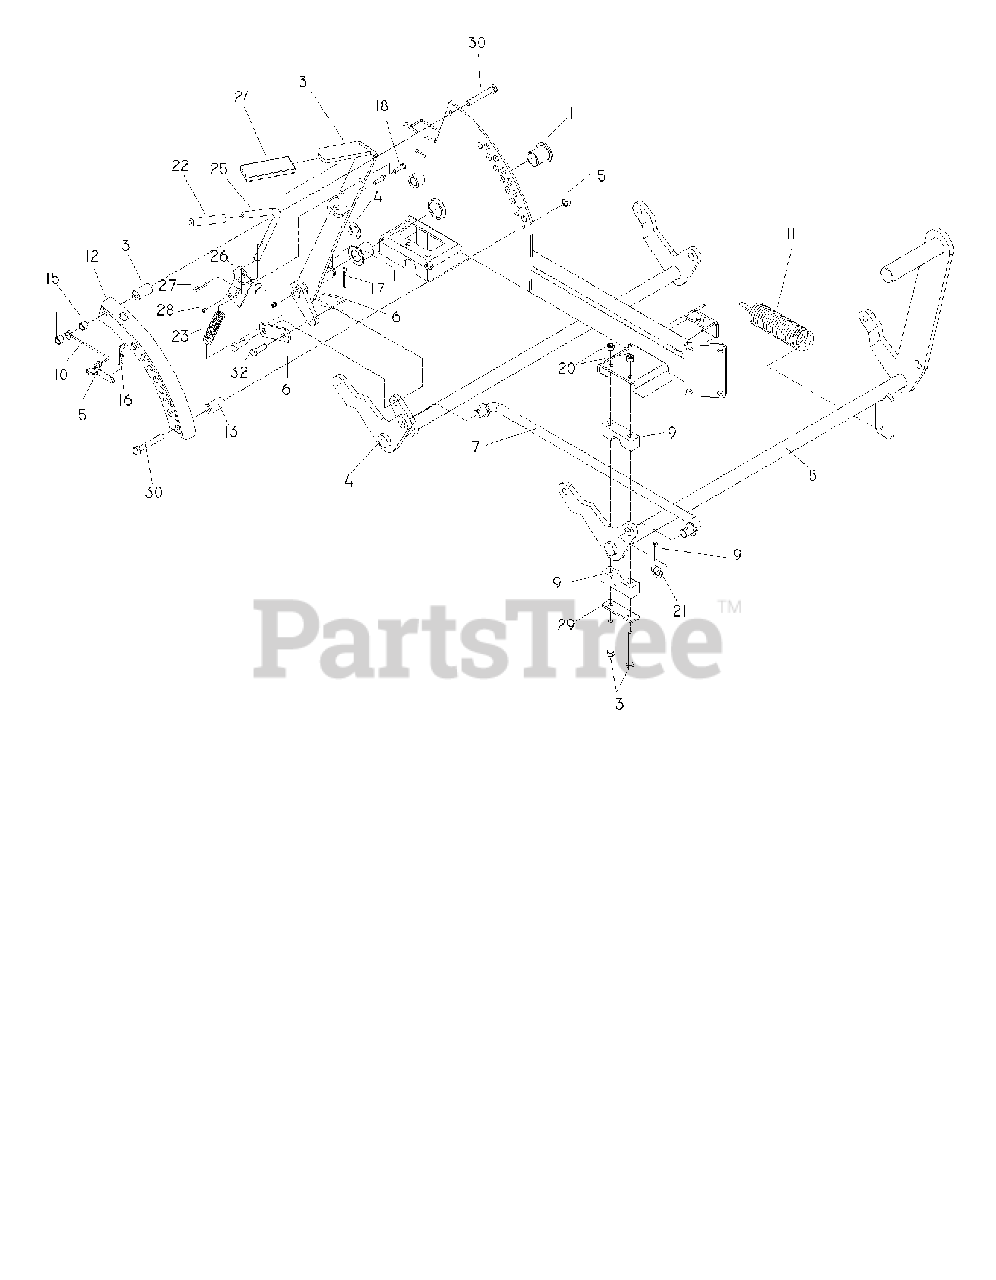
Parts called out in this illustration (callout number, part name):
1	BUSHING, FLANGED
3	HCS 5/16C X 2-3/4
4	E-RING 7/8
5	HITCH PIN
6	LIFT ARM
7	CROSS LINK
8	SHAFT, LIFT-FRONT
9	PILLOW BLOCK
10	LANYARD
12	ADJUSTMENT PLATE WLDMT
13	DECK LIFT SPACER
14	SHAFT, LIFT-REAR
15	NUT 3/8-16 NYLOC
16	HAIRPIN #4
17	COTTER PIN 1/8 X 3/4
18	HCS 1/4C X 3/4 HCS
19	COTTER PIN
20	NUT 5/16 NYLOC
21	BUSHING
26	PIN MT, UPPER
27	ROLL PIN
28	NUT 1/4C CENTER LOCK
29	REINFORCEMENT BAR
30	HCS 3/8C X 2 1/2
31	LIFT LEVER WELDMENT
32	CLEVIS PIN 3/8 X 1 1/8
